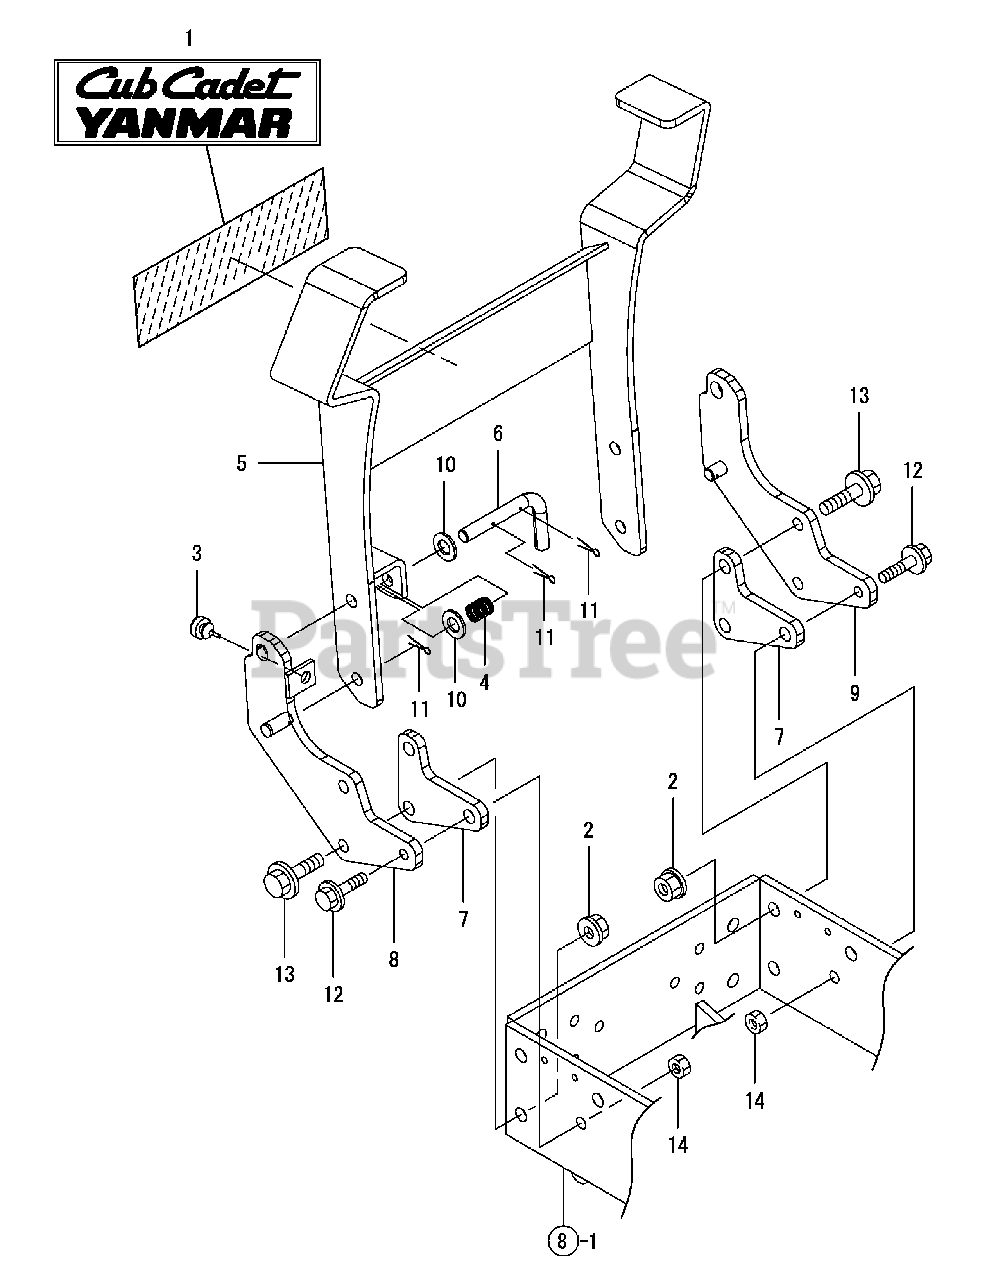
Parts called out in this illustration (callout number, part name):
1	LABEL, GRILL GUARD
2	NUT W/WASHER 12
3	STOPPER, PEDAL
4	SPRING, SEAT STAY
5	GUARD ASSY, GRILLE
8	BRACKET ASSY, L
9	BRACKET ASSY, R
10	WASHER 14,POLISHED
11	COTTER PIN 2.5X30
12	BOLT M10X 40 PLATED
